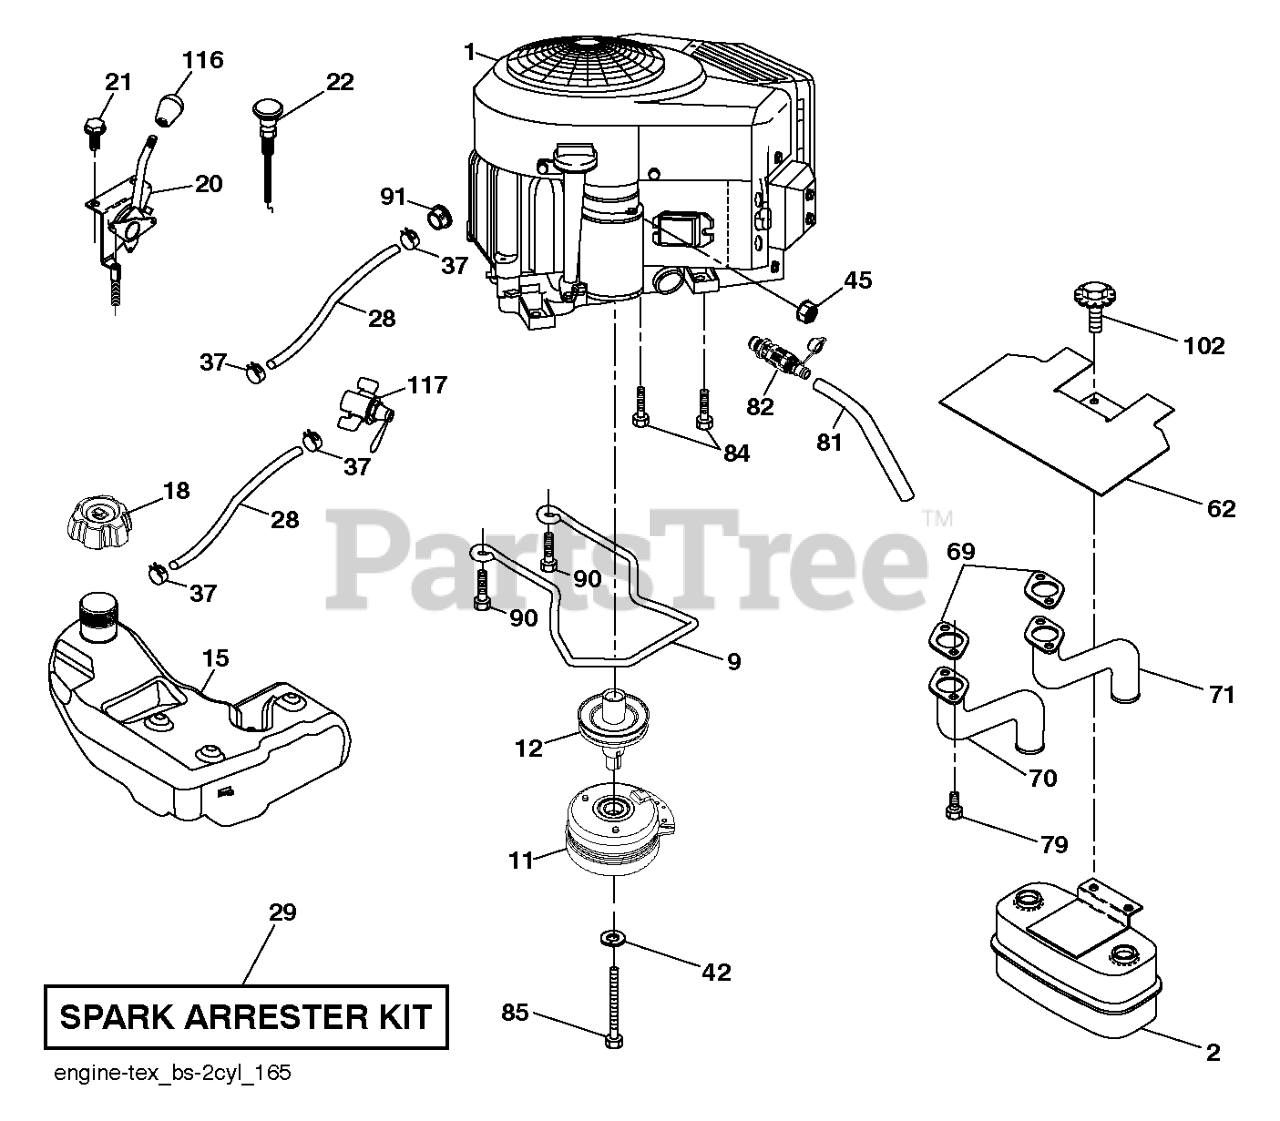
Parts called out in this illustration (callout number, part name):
2	MUFFLER.ASM.TWIN.MNTG.BRACKET
9	KEEPER.BELT.ENG.4.25"2.BLT.431
11	CLUTCH. 5.0 PD. 2.5 OFFSET
12	PULLEY.EXTENDED.SHAFT.GROUND
18	CAP.ASSY.FUEL.3".N-EPA.GRY.498
20	CONTROL.THROTTLE.PRO.
21	SCREW.#10 X 0.750.BOS
22	CONTROL, CHOKE
28	HOSE 1/4" LOW PERMEATION FUEL
29	KIT.SPARK ARRESTOR 794945 B&S
37	HOSE CLAMP
42	WASHER 7/16 LOCK
45	NUT
62	SHIELD.HEAT.MUFFLER
69	GASKET.MUFF 806237 NOW 806425
70	EXHAUST.TUBE.MUFFLR.LH.VANG
71	EXHAUST.TUBE.MUFFLR.RH.VANG
79	SCREW.SOCKET HD.5/16-1
81	TUBE, DRAIN OIL ASM.
82	VALUE.OIL.DRAIN
84	SCREW.3/8-16
85	BOLT.HEX.7/16-20X5.GR5.GREEN
90	SCREW 3/8-16X1
91	BUSHING.1.375OD
102	SCREW
116	KNOB - SHIFT
117	VALVE FUEL RESERVE
